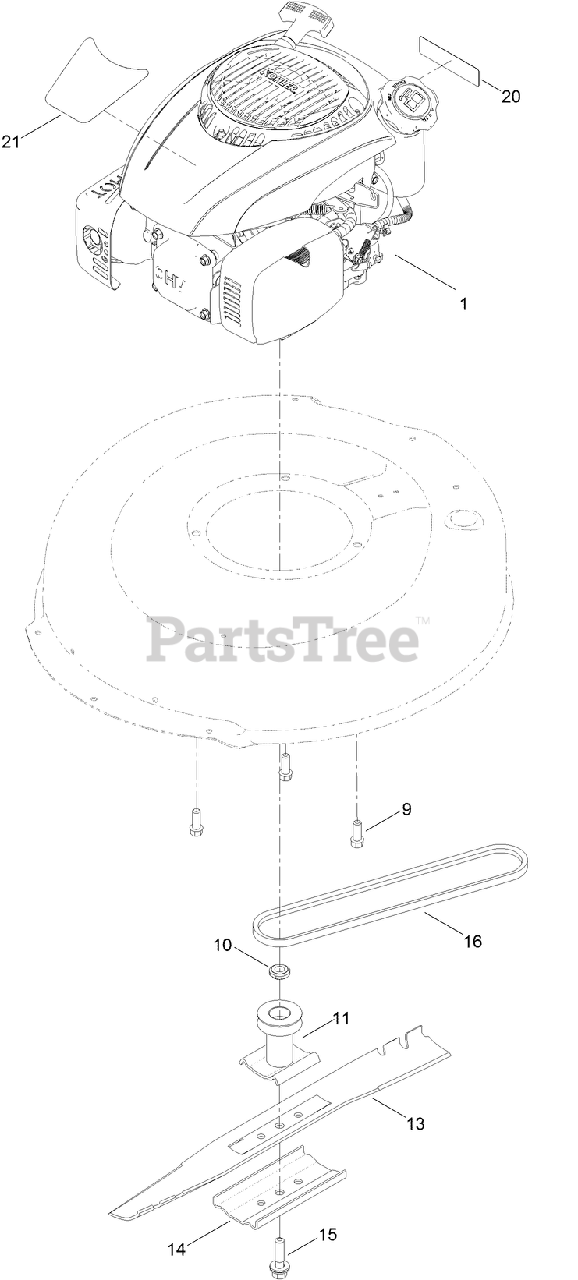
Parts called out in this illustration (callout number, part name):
9	SCREW-TAPTITE
10	SPACER-DRIVER
11	DRIVER-BLADE
14	SUPPORT-BLADE
15	BOLT-BLADE
20	DECAL-ARRESTER, SPARK
